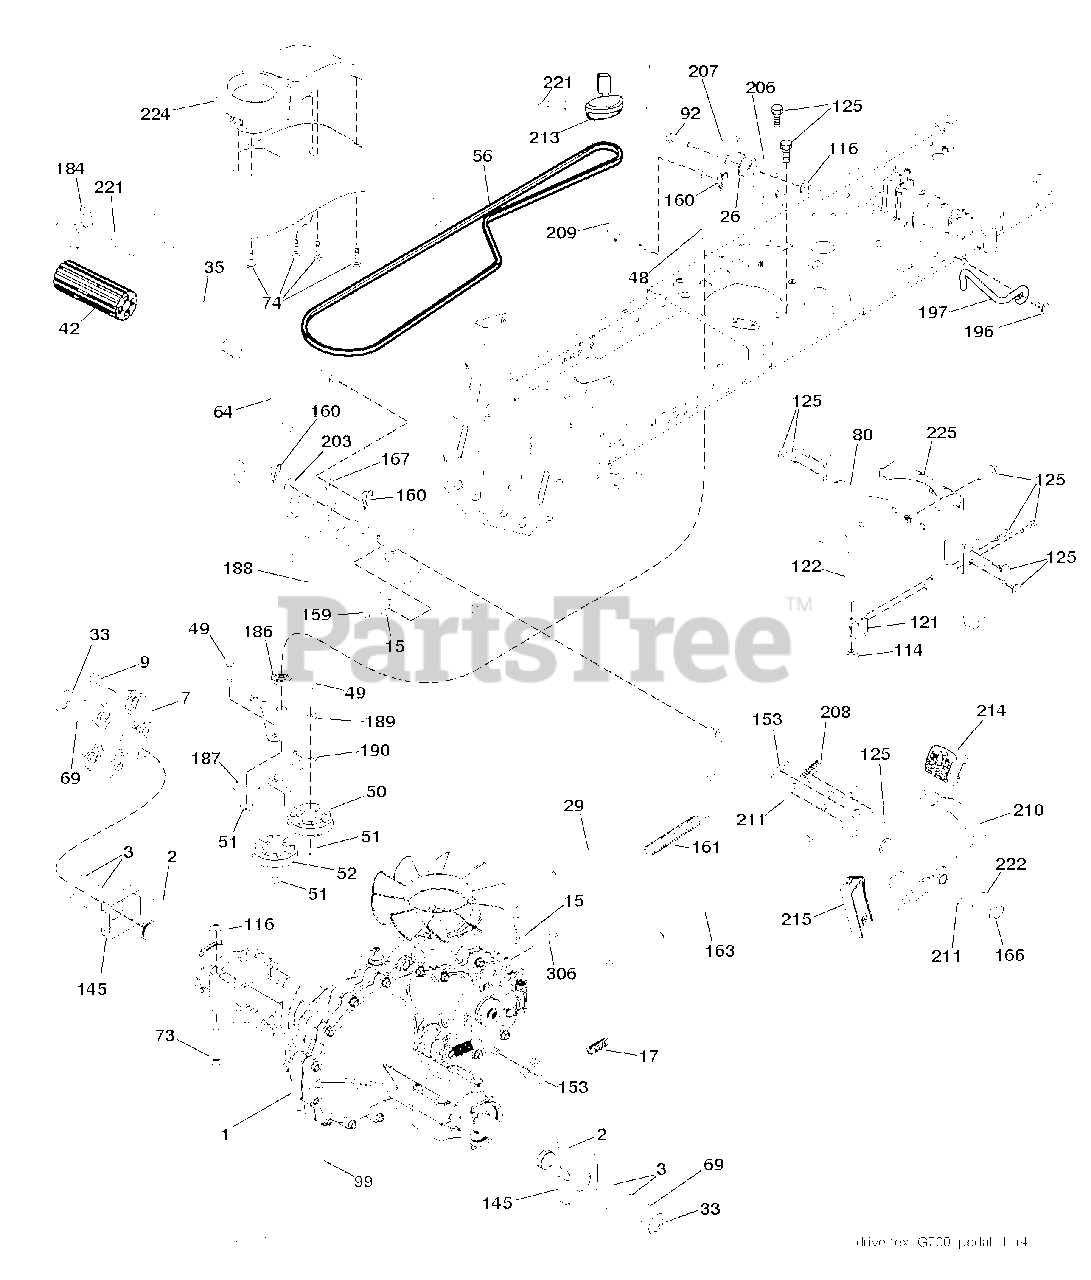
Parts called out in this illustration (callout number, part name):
3	WASHER T
7	HUB.ASM.WHEEL.REAR.23"TEX
9	HUB BOLT
15	WASHER
26	SPRING.RETURN.CRUISE
33	E RING HYT
35	ROD.BRKAE.PARKING.STEALTH
48	BOLT.3/8-16X1.50
50	IDLER.FLAT.910.OFFSET
52	IDLER.V-GROOVE.910.OFFSET
64	SHAFT.ASM.PEDAL.BRK.CNTR
74	SCREW.HI-LO.CONSOLE
114	NUT.71038.31-18.HEX.NYLOCK
116	NUT LOCK HEX FLANGE 5/16-18
159	COTTER PIN
160	RETAINER CLIP
161	SPRING, RETURN LT
166	NUT.PUSH.625
167	LATCH.BRAKE.SPRING
186	SPACER.RETAINER
188	LINK.CLUTCH.GROUND.DRIVE
196	SCREW 3/8-16X1
197	BRKT.ANIT-ROTATION.CLU
206	BRKT.MOUNT.LATCH.CRUIS
207	LATCH.CONTROL.CRUISE
208	GEAR.SECTOR.CONTROL.CR
209	ROD.CONTROL.CRUISE.STEALTH.TEX
210	ROCKER.ASM.PEDAL.CONTR
211	BEARING.NYLON
213	KNOB.CONTROL.CRUISE
214	PAD PEDAL FORWARD
215	PEDAL.REVERSE.TEX.GT.4
221	RETAINER.SPRING.CLIP.H
222	WASHER 21/32 X 1-1/4 X 10 GA.
224	CONSOLE.TOOLBOX.PCH.ERGO.BLACK
